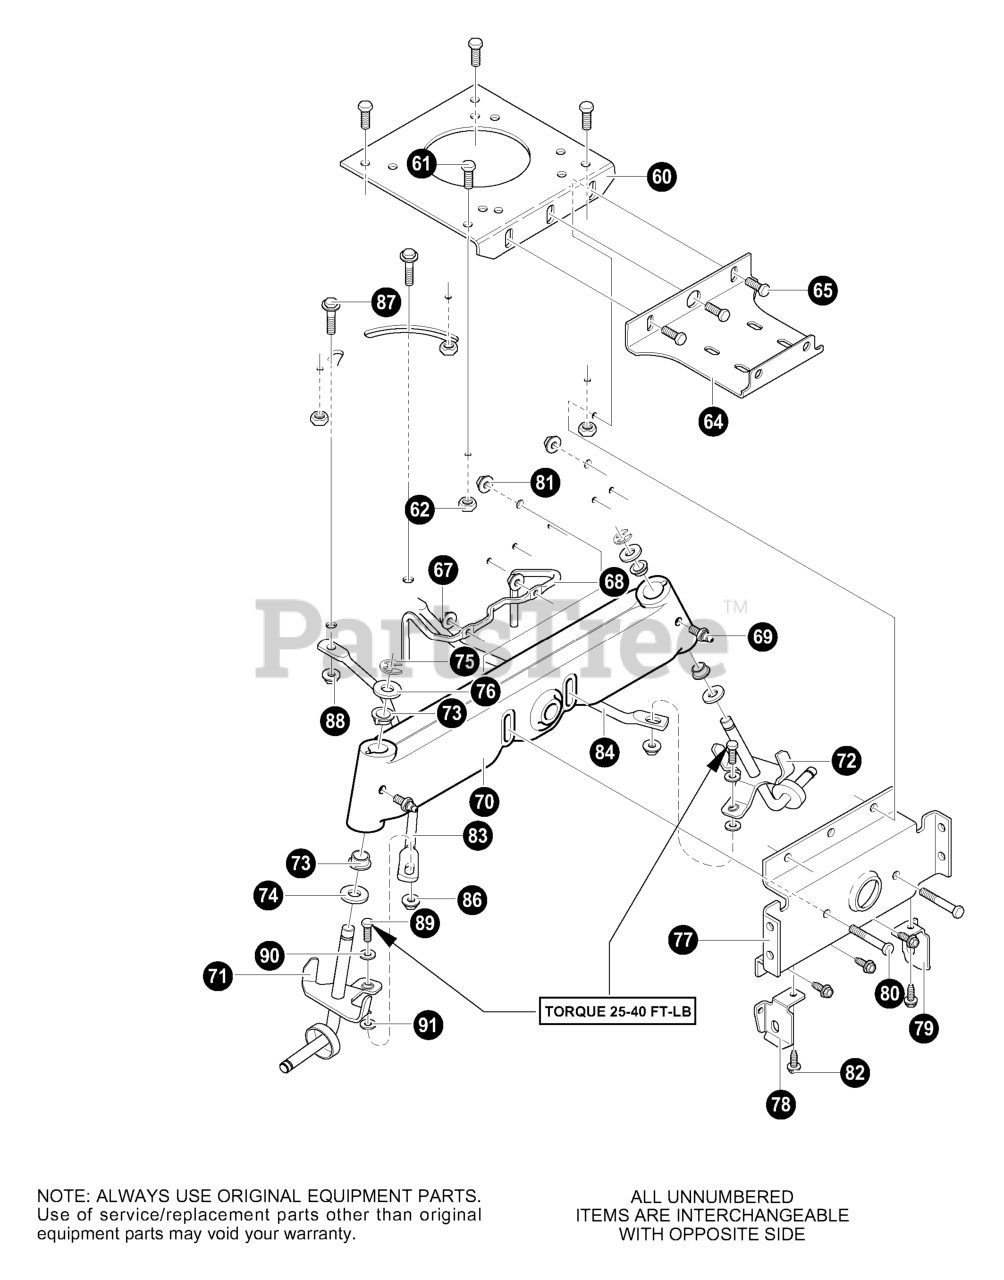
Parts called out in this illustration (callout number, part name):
60	ENGINE PLATE
61	SCREW, 5/16-18 x 0.75 HHWATAP
62	NUT, 5/16-18 WDFLLK 15X88
64	BRACKET, MUFFLER MOUNT
65	SCREW, 5/16-18 x 0.75 HHWATAP
67	NUT, 5/16-18 HEXWDFLLK WHIZ
68	GUIDE-STACK PULLEY BELT
69	ZERK, GREASE FITTING
70	AXLE, CAST MACHINED REBA
71	SPINDLE, LONG RH
72	SPINDLE, LONG LH
73	BEARING, SPINDLE
74	WASHER, .766IDX1.62ID
75	E-RING .574IDX.050X.750SH 11X3
76	WASHER, FLAT .765 x 1.81 x .059
77	HANGER, AXLE
78	HANGER, DECK RH
79	HANGER, DECK LH
80	SCREW, 5/16-18 x 3.00
81	NUT, 5/16-18 WDFLLK 15X88
82	SCREW, 5/16-18 x 0.75 HHWATAP
83	DRAG LINK RH
84	DRAG LINK LH
86	NUT, 3/8-16 HWDFLLK MACK 15X84
87	SHOULDER BOLT 9X57
88	NUT, 3/8-16 HWDFLLK MACK 15X84
89	SCREW, 3/8-16 x 1.50
90	WASHER FLAT .391X1.00X.083
91	WASHER FLAT .406X.81X16GA
